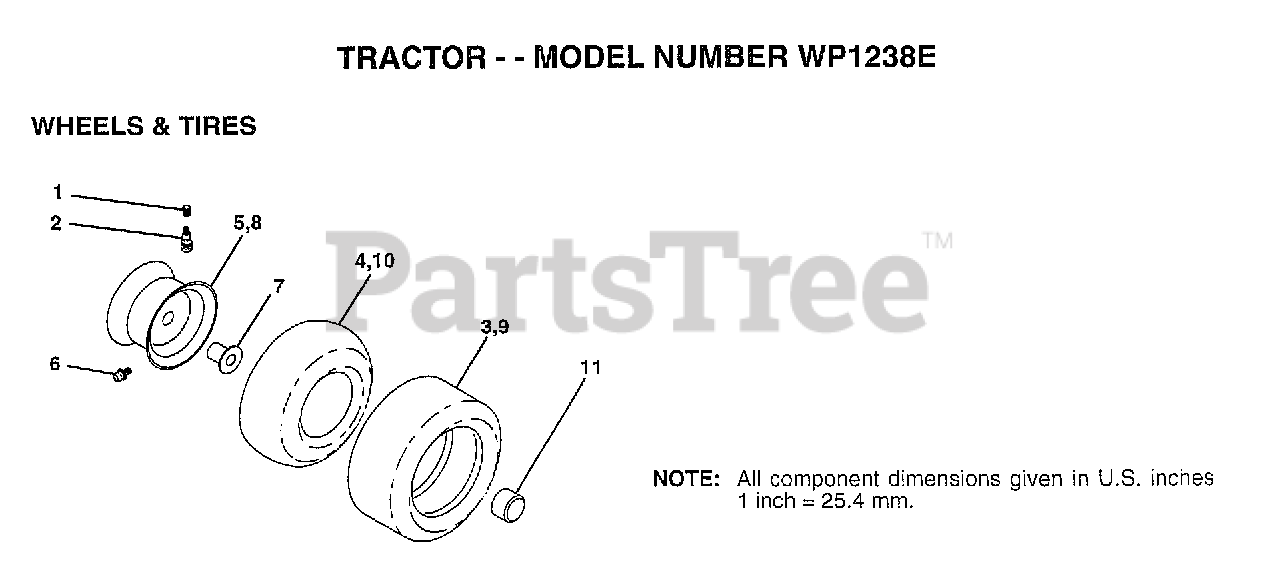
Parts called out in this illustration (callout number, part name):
1	VALVE CAP
2	VALVE STEM LT
4	TUBE.5.3/4.5/6
5	"RIM,FRT T"
6	FITTING LT
7	"FLANGE, BEARING"
8	"RIM 8"""
10	TUBE.18X9.5-8
11	HUB CAP
